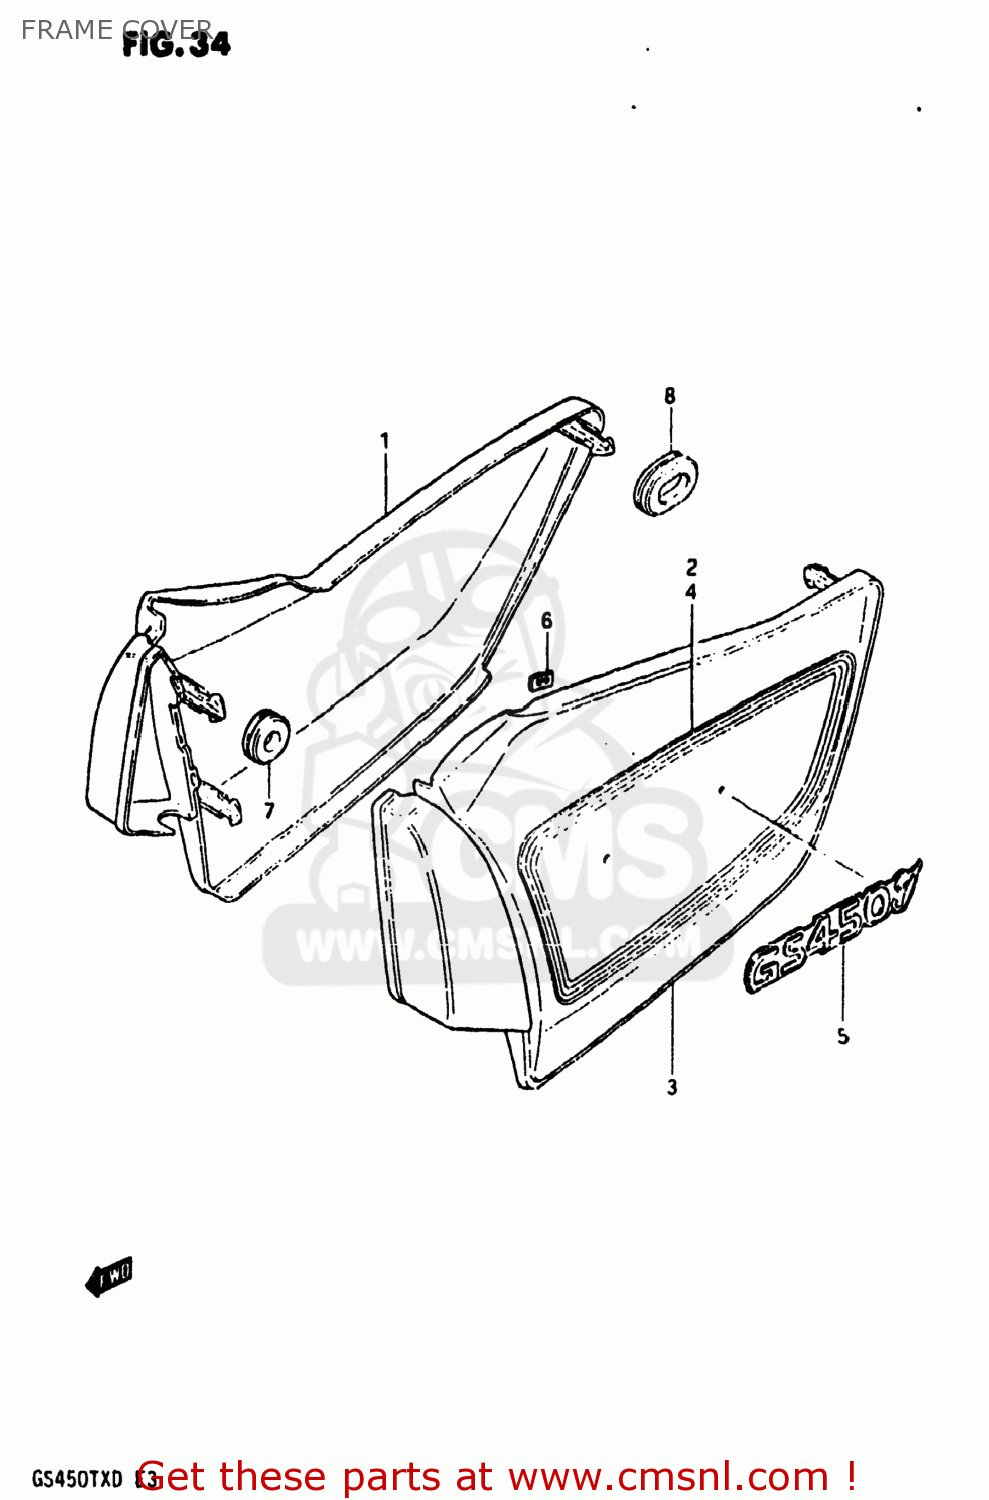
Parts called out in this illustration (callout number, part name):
1	COVER,FRAME,RIGHT
2	TAPE SET,FRAME COVER
3	COVER,FRAME,LEFT
4	TAPE SET,FRAME COVER
5	EMBLEM,FRAME COVER
6	NUT
7	CUSHION
8	CUSHION
